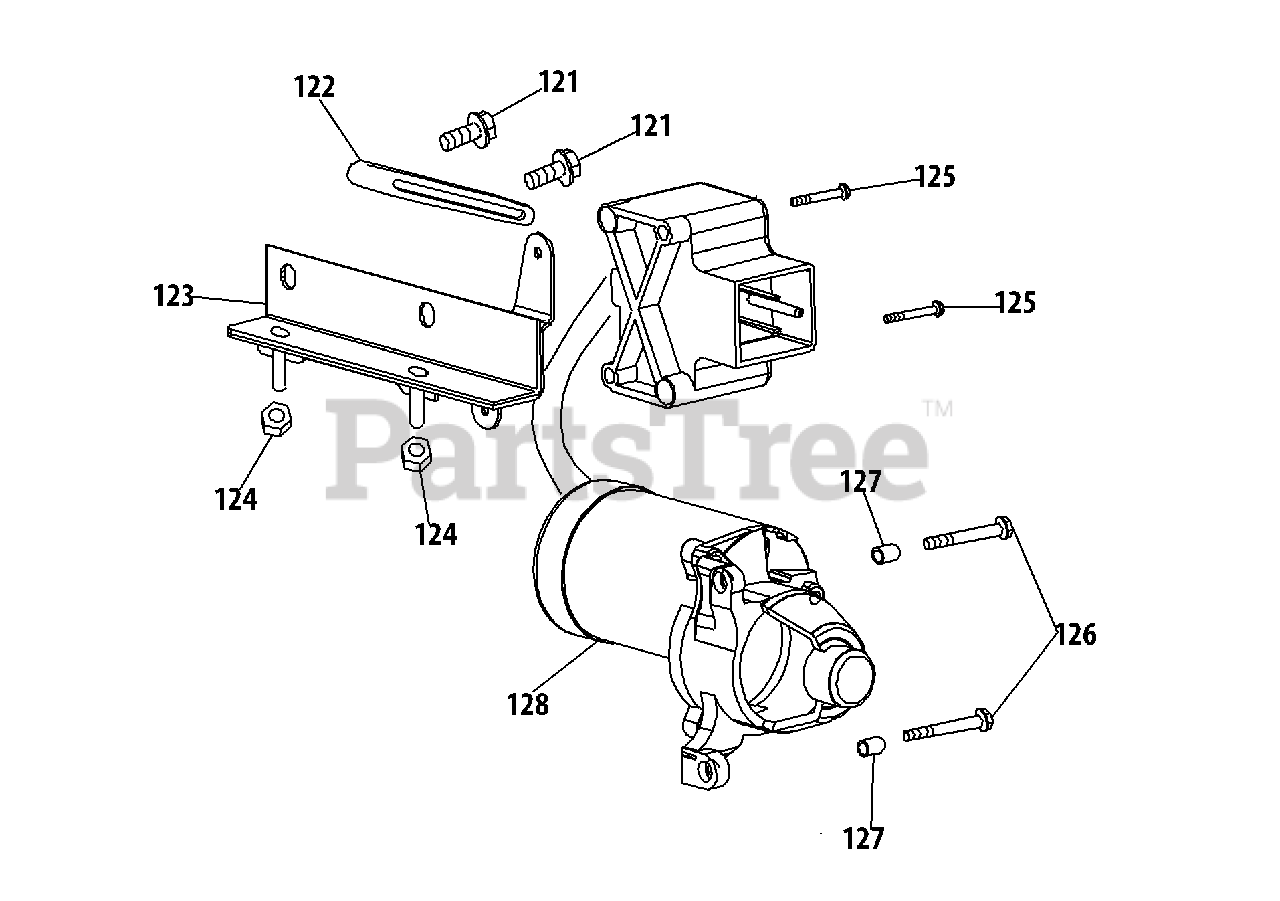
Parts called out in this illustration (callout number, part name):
121	Bolt M6×10
122	Flexible Clamp
123	Switch Housing Mounting Bracket
124	Nut,M6
125	Bolt M4×55
126	Bolt M6×32
127	Dowel Pin 8×8
128	Electric Starter
